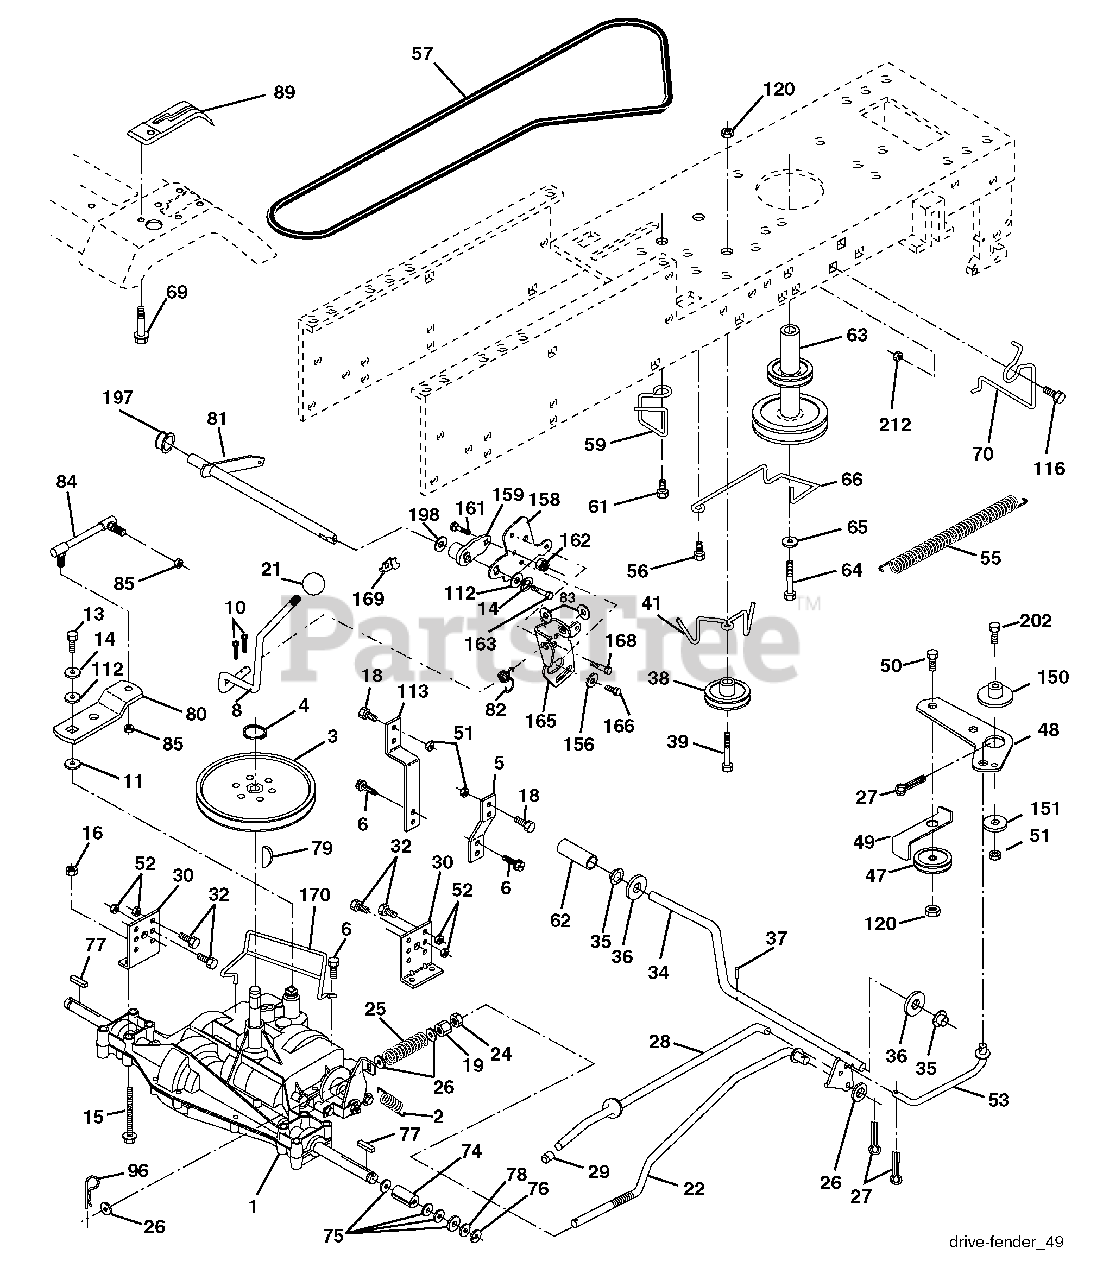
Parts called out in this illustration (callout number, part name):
2	Spring Return Brake T/a Zinc
3	Pulley Transaxle 18" tires
4	Ring Retainer # 5100-62
5	Strap Torque 30 Degrees
6	Screw 5/16-18 X 3/4
8	Rod Shift Fender Adjust Lt
10	Pin Cotter 1/8 X 1 Cad
11	Washer Plate Shf 388 Sq Hole
13	Bolt 1/4-28 Unf Gr. 8 W/Patch
14	Washer Lock Hvy Helical
15	Bolt Hex FLGHD 5/16-18 Gr. 5
16	Nut Lock Hex w/ins 5/16-18
18	Bolt, Fin Hex 3/8-16 unc x 1 Gr.
19	Nut Lock 3/8-16 Unc
21	Knob
22	Rod Brake Blk Zinc 26 840
24	Nut Hex Jam 3/8-16 unc
25	Spring Rod Brake 2 00 Zinc
26	Washer 13/32 x 13/16 x 16 Ga.
27	Pin Cotter 1/8 x 3/4 Cad
28	Rod Brake Parking LT/YT
29	Cap Brake Parking
30	Bracket Mtg Transaxle
32	Bolt Hex Hd 5/16-18 unc x 3/4
34	Shaft Asm Pedal Foot
35	Bearing Nylon Blk 629 Id
36	Washer 21/32 x 1 x 16 Ga.
37	Pin Roll 3/16 X 1"
38	Pulley Composite Flat
39	Bolt RDHD 3/8-16 unc x 2-3/4
41	Keeper Belt Flat Idler
47	Pulley Idler V Groove Plastic
48	Bellcrank Asm
49	Retainer Belt Style Spring
50	Bolt Carr. Sh. 3/8-16 x 1-1/2 Gr.
51	Nut Crownlock 3/8-16 unc
52	Nut Crownlock 5/16-18 unc
53	Link Clutch
55	Spring Return Clutch 6 75
56	Screw 3/8-16 x 1-1/4
57	V-Belt Ground Drive 95 25
59	Keeper Belt Span Ctr
61	Screw 3/8-16 x .875
62	Cover Pedal Blk Round
63	Engine Pulley
64	Bolt Hex
65	Washer Lock Hvy Hlcl Spr 7/16
66	Keeper Belt Engine Foolproof
69	Screw Hex wsh HiLo 1/4 x 1/2 unc
70	Guide Belt Mower Drive RH
74	Spacer Axle
75	Washer 25/32 x 1 1/4 x 16 Ga.
76	E-ring #5133-75
77	Key Square 2 0 x 1845/ 1865
78	Washer 25/32 x 1-5/8 x 16 Ga.
79	Key Woodruff #9 3/16 x 3/4
80	Arm Shift
81	Shaft Asm Cross Tapered PMST/20
82	Spring Torsion T/a
83	Washer 17/32 x 3/4 x 16 Ga.
84	Link Transaxle PMST/18" Zinc
85	Nut Lock Center 1/4 - 28 FNTHD
89	Console Shift STLT
96	Retainer Spring 1"
112	Washer 9/32 x 3/4 x 10 Ga.
113	Strap Torque LT
116	Bolt Rdhd Sq Neck 3/8-16 x 1
120	Nut Lock Flg. 3/8-16 unc
150	Spacer Retainer
151	Washer 13/32 x 2 x 10
156	Washer Srrted 5/16ID x 1.125
158	Bracket Shift Mount
159	Hub Tapered Flange Shift Lt
161	Bolt Rdhd Sqnk 1/4-20 x 3/4
162	Nut Crownlock 1/4-20 unc
163	Bolt Hex Fin 1/4-20 unc x 1 Gr. 5
165	Bracket Pivot Lever
166	Screw 5/16-18 x 5/8
168	Bolt Shoulder 5/16-18 x .561
169	Plate Fastening
170	Keeper Belt Transaxle Gear
197	Nyliner Snap-In
198	Washer Nyliner
202	Bolt RdHd 3/8-16 unc x 1-3/4 Gr. 5
212	Nut Hexfl ange Lock
